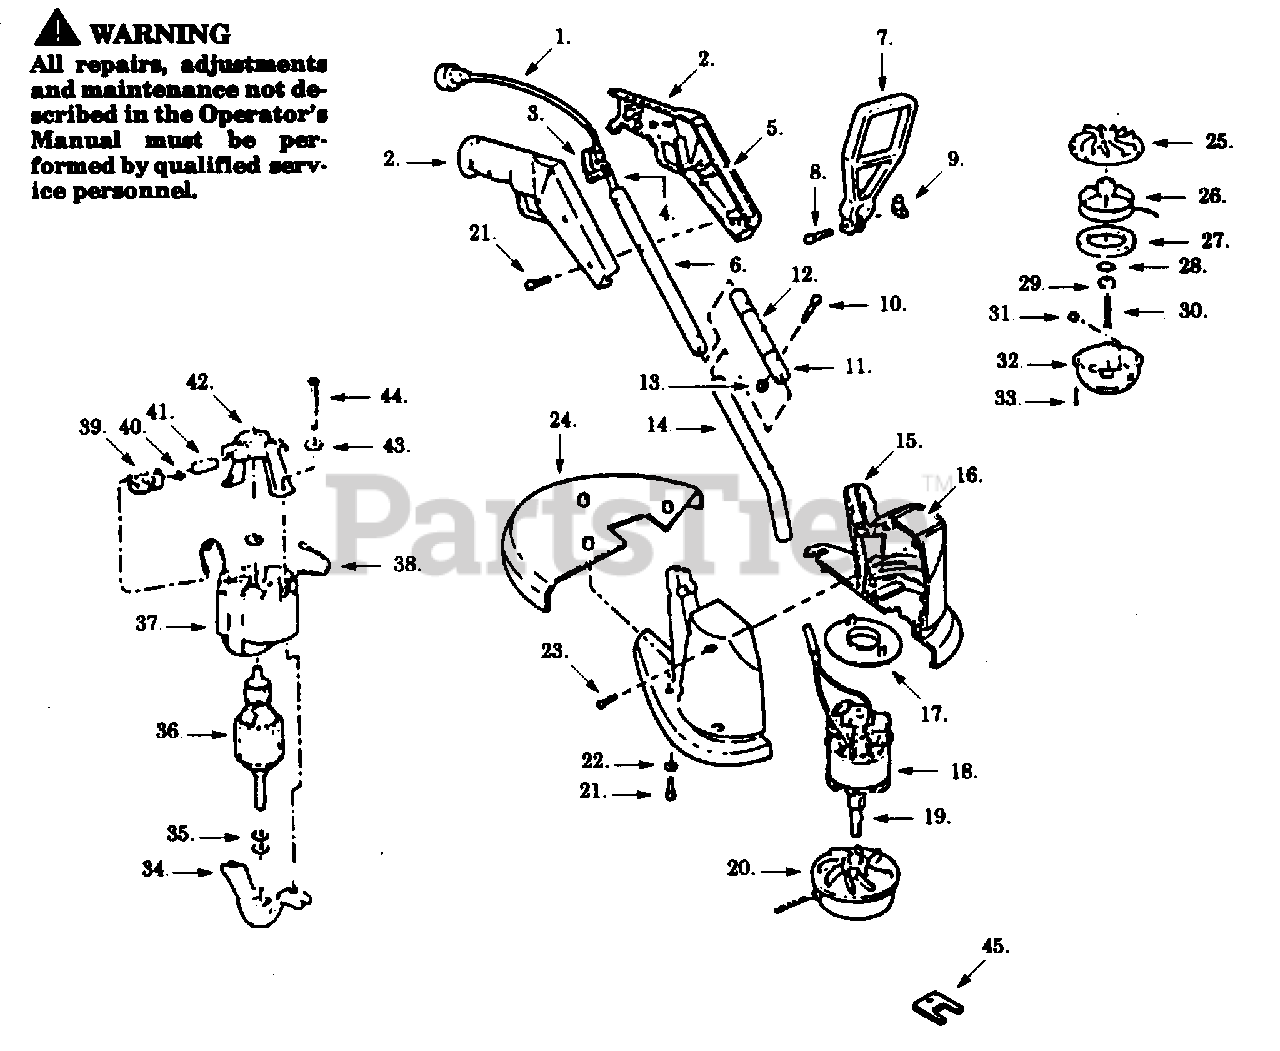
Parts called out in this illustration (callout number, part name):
1	Power Cord
2	Handle Set
3	Trigger Switch
5	Handle Label
6	Upper Tube
7	Assist Handle Ass'y.
9	Wing Nut
11	Outer Tube
12	Warning Label
14	Lower Tube
15	Housing Set
16	Housing Top Label
17	Air Baffle
19	Shaft Adapter
20	Cutting Head Ass'y.
24	Guard & Blade Ass'y.
25	Rear Plate
26	Spool & Line
27	Foam Pad
29	Adapter Nut
32	Hub Ass'y.
33	Cotter Pin
34	Endbell Ass'y. (Drive)
36	Armature Ass'y.
37	Field Ass'y.
38	Leadwire Ass'y.
39	Brush Holder Ass'y.
40	Brush Spring
42	Endbell Ass'y. (Brush)
43	Lockwasher
45	Spanner Wrench
